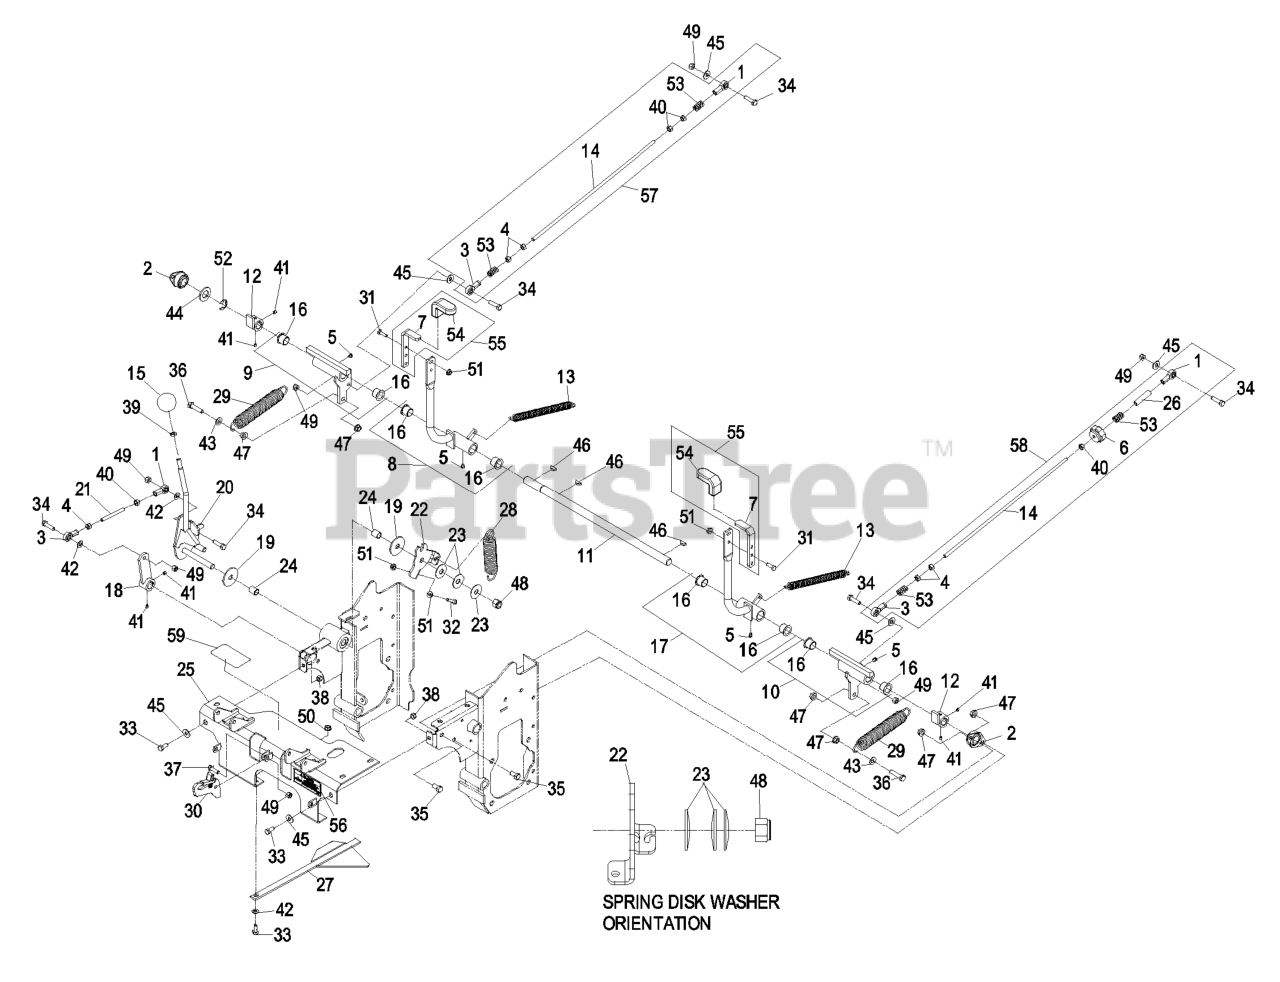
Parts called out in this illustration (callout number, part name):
1	BALLJOINT-RH
2	BEARING-FLANGE, SIDE
3	BALLJOINT-LH
4	NUT
6	KNOB-TRACKING
7	ASM,HANDLE W/GRIP
8	ASM,STEERING LEVER RH W/B
9	ASM,ACTUATOR RH W/BEARING
10	ASM,ACTUATOR LH W/BEARING
11	SHAFT,SPEED CONTROL
12	WLD,HUB SPEED CONTROL
13	SPRING,EXTENSION
14	LINKAGE,ROD LH STEERING (
15	KNOB-BALL, SPEED CONTROL
16	BEARING-FLANGE, IGLIDE
17	ASM,STEERING LEVER LH W/B
18	WLD,CONTROL ARM (PLATED)
19	DISC-FRICTION
20	WLD,SPEED CONTROL LEVER(P
21	ROD,THREADED CONTROL LINK
22	PLATE,SPEED CONTROL FRICT
23	WASHER-DISC, SPRING
24	BEARING,PLASTIC 1/2"
25	Asm, Console W/Decals
27	GUIDE-PLENUM
28	SPRING,EXTENSION (PLATED)
29	SPRING-EXTENSION
31	SCREW-HH
32	SCREW-HH
33	SCREW-HH
34	SCREW-HH
35	SCREW-HH
36	SCREW-HH
37	SCREW-HH
38	NUT-HEX
39	NUT-JAM
40	NUT-HEX
41	SCREW-SET, HSH
42	WASHER-PLAIN
43	WASHER-FLAT
44	WASHER-FLAT
45	WASHER-FLAT
46	KEY-WOODRUFF
47	NUT-HHF, WHIZ
48	NUT-HEX
49	NUT-LOCK, NI
53	SPRING-COMPRESSION
54	GRIP-HANDLE, STEERING
55	ASM,HANDLE W/GRIP
56	DECAL-DRIVELINE
57	ASM,RH PUMP LINKAGE
58	ASM,LH PUMP LINKAGE
59	DECAL,WHEEL MOTOR RELEASE
